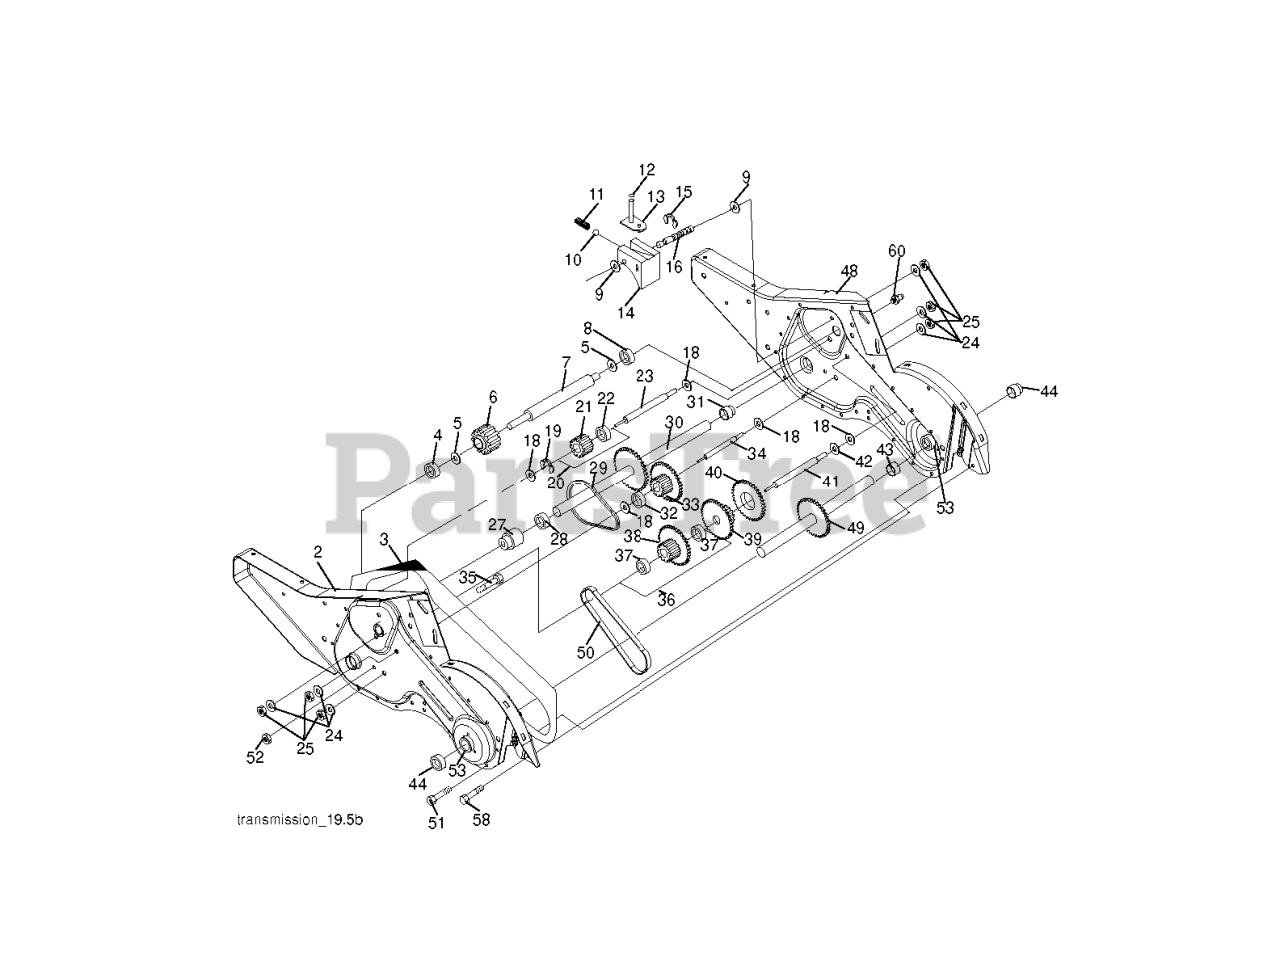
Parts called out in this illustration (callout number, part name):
1	TRANSMISSION ASM.
2	GEARCASE.ASM.CRT.LH.W/BEARING
3	GASKET
4	NEEDLE BRNG LT
5	THRUST WASHER
6	GEAR.PINION.INPUT
7	SHAFT.INPUT."D".TILLER
8	BEARING TI
9	WASHER, SEAL (2 2)
10	STEEL BALL KIT
11	SPRING-SHIFT CRT
13	BRACKET ASM.SHIFT.CRT
14	SHIFT FORK TI
16	SHAFT.SHIFTER.TILLER
20	GEAR ASSY CRT
21	GEAR-REV IDLR CRT
22	NEEDLE BEARING TI
24	LOCKWASHER
25	NUT.ASF.HEX.7/16
27	BEARING, SHAFT LH CRT
30	GROUND SHAFT ASS'Y
31	BEARING, SHAFT RH CRT
33	SPRCKT 8 GEAR CRT
34	SHAFT.SECONDARY.REDUCTION.CRT
35	SCRW WHIZ LOK CRT
36	SPROCKET.ASM.W/BEARING.TILLER
37	BEARING
38	SPROCKET, TINE
41	SHAFT.REDUCTION.TILLER
42	BRNG RACE T
44	SEAL ASM, OIL
48	GEARCASE.ASM.CRT.RH.W/BEARING
49	TINE SHAFT
50	CHAIN.TILLER
51	SCREW
53	KIT.BEARING.TILLER.
58	BOLT SHOULDER 1/4-20 UNC X.875
60	FITTING.GREASE.TAPERED
